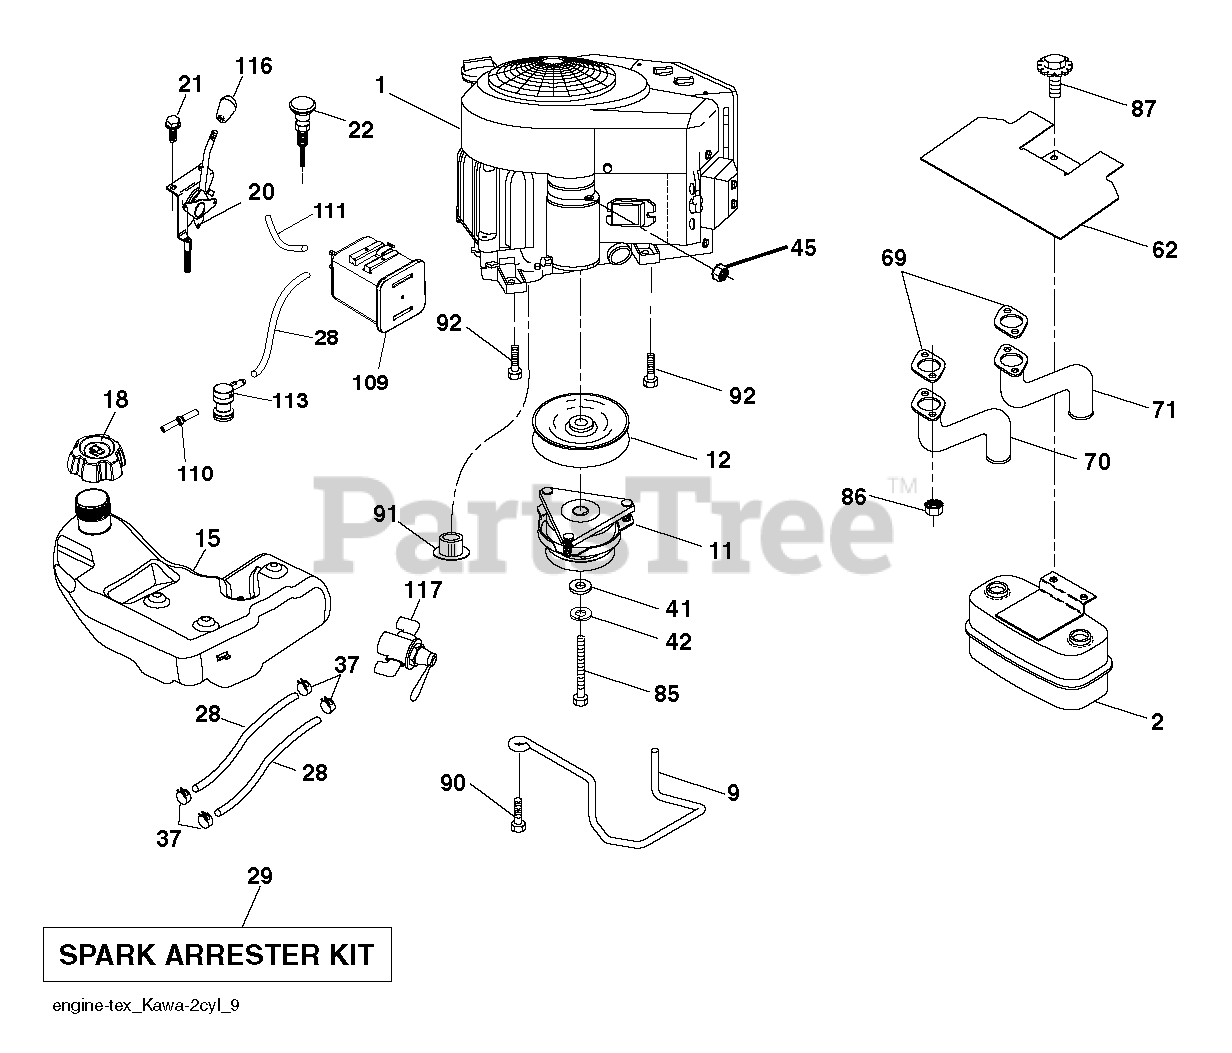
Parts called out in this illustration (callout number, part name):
2	MUFFLER.TWIN.CYL.LOW.TONE
9	KEEPER BELT ENGINE
11	CLUTCH MZ ZTR GT.48/54"1.125"
12	PULLEY ENGINE
15	TANK.ASM.4.GAL.CARB.2.PORT.REA
18	CAP.ASM.FL.RITCH.3"E10.SYM.498
20	CONTROL.THROTTLE.PRO.
21	SCREW.#10 X 0.750.BOS
22	CONTROL.CHOKE.ERGO.PUSH-IN.BLA
28	LINE.FUEL.64"REAR.EMIS
29	KIT.SPARK ARRESTOR 794945 B&S
37	HOSE CLAMP
42	LOCKWASHER
45	NUT
62	SHIELD.HEAT.MUFFLER
70	TUBE.EXHAUST.LH.FR961/FR730
71	TUBE.EXHAUST.RH.FR961/FR730
85	BOLT HEX 7/16-20 X 3.75 GR. 5
86	NUT.HEX.FLANGE.TOPLOCK
87	BOLT.5/16-18UNCX1.W/SEMS.BLK
90	SCREW 3/8-16X1
91	BUSHING.1.375OD
92	SCREW 3/8-16X1
109	CANNISTER, CARBON
110	VALVE.ASM.ANTI-SLOSH
111	RP PURGE LINE
113	VALVE.SLANT.CARTRDG.90 DEG.TEX
116	KNOB - SHIFT
117	VALVE FUEL RESERVE
